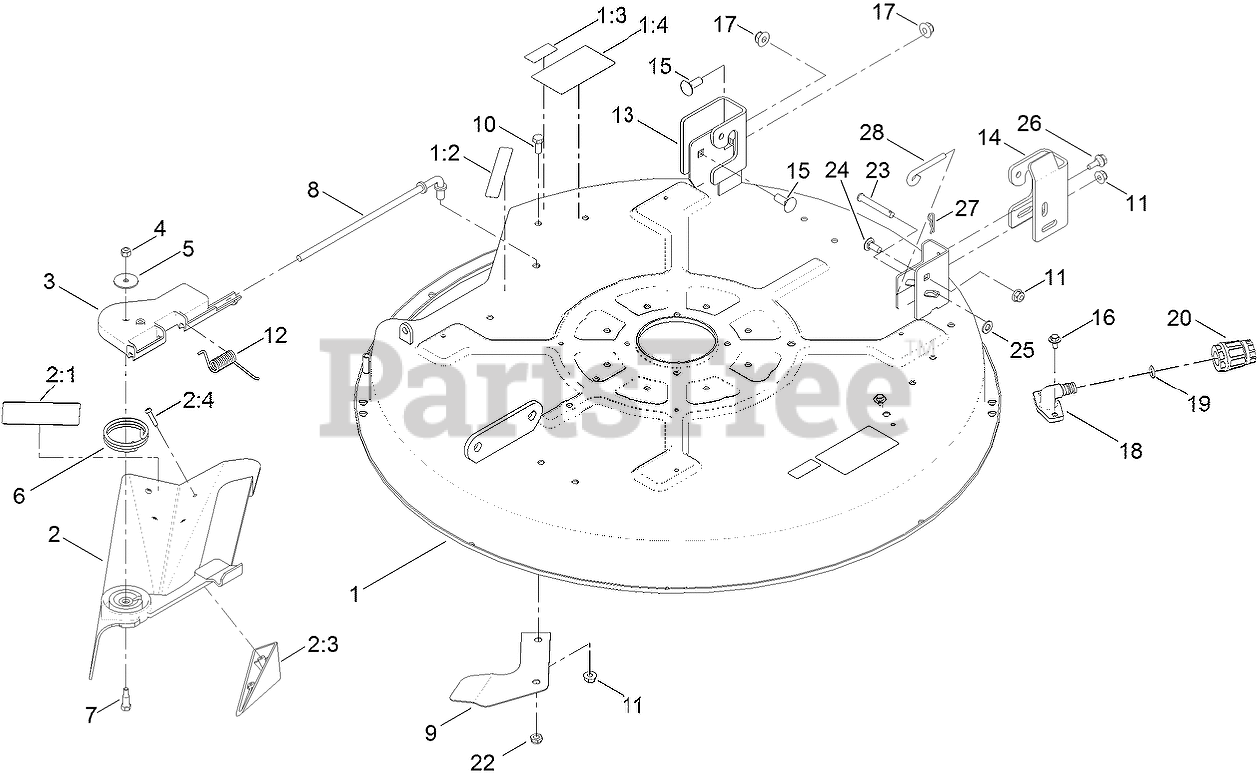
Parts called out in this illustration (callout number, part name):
1	32 INCH DECK AND DECAL ASM
1:2	DECAL-DANGER
1:3	DECAL-DANGER
1:4	DECAL-DANGER
2	32 INCH DEFLECTOR ASM
2:1	DECAL-DANGER
2:3	KICKER
2:4	SCREW-PPH
3	PIVOT-HINGE, DEFLECTOR
4	NUT-LOCK, NI
5	WASHER-FLAT
6	SPRING-TORSION
7	BOLT-SHOULDER
8	ROD-PIVOT
9	RAMP-DEFLECTOR
10	SCREW-HH
11	NUT-HF, NI
12	SPRING-TORSION
13	BRACKET-HANGER, RH
14	BRACKET-HANGER, LH
15	BOLT-CARR
16	SCREW-HHFTF
17	NUT-HF, NI
18	FITTING-WASHOUT
19	O-RING
20	CONNECTOR-HOSE
22	NUT-LOCK, NI
23	PIN-CLEVIS
24	SCREW-CARR
25	WASHER-PLAIN
26	SCREW-SHOULDER, HHF
27	PIN-COTTER
28	ROD-LEVEL, DECK
